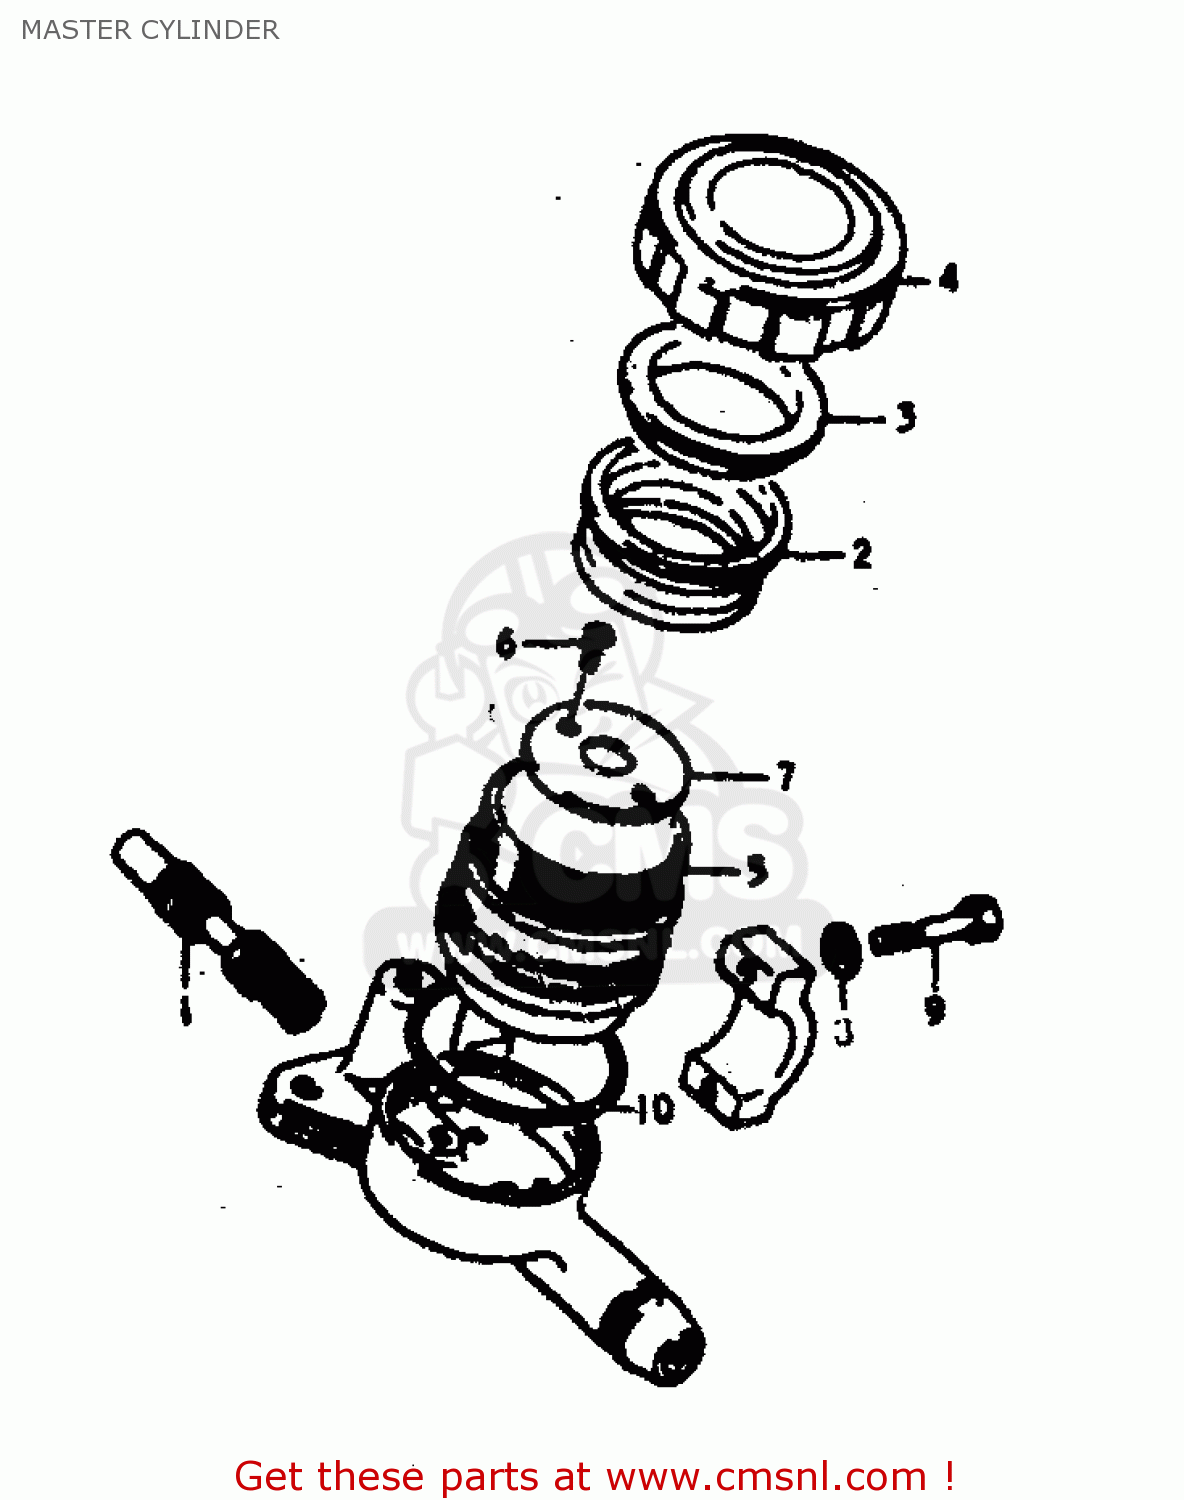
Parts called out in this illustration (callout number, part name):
1	PISTON & CUP SET
2	DIAPHRAGM
3	PLATE,DIAPHRAGM
4	CAP
5	RESERVOIR
6	SCREW,MASTER CYLINDER
9	BOLT
10	O RING
